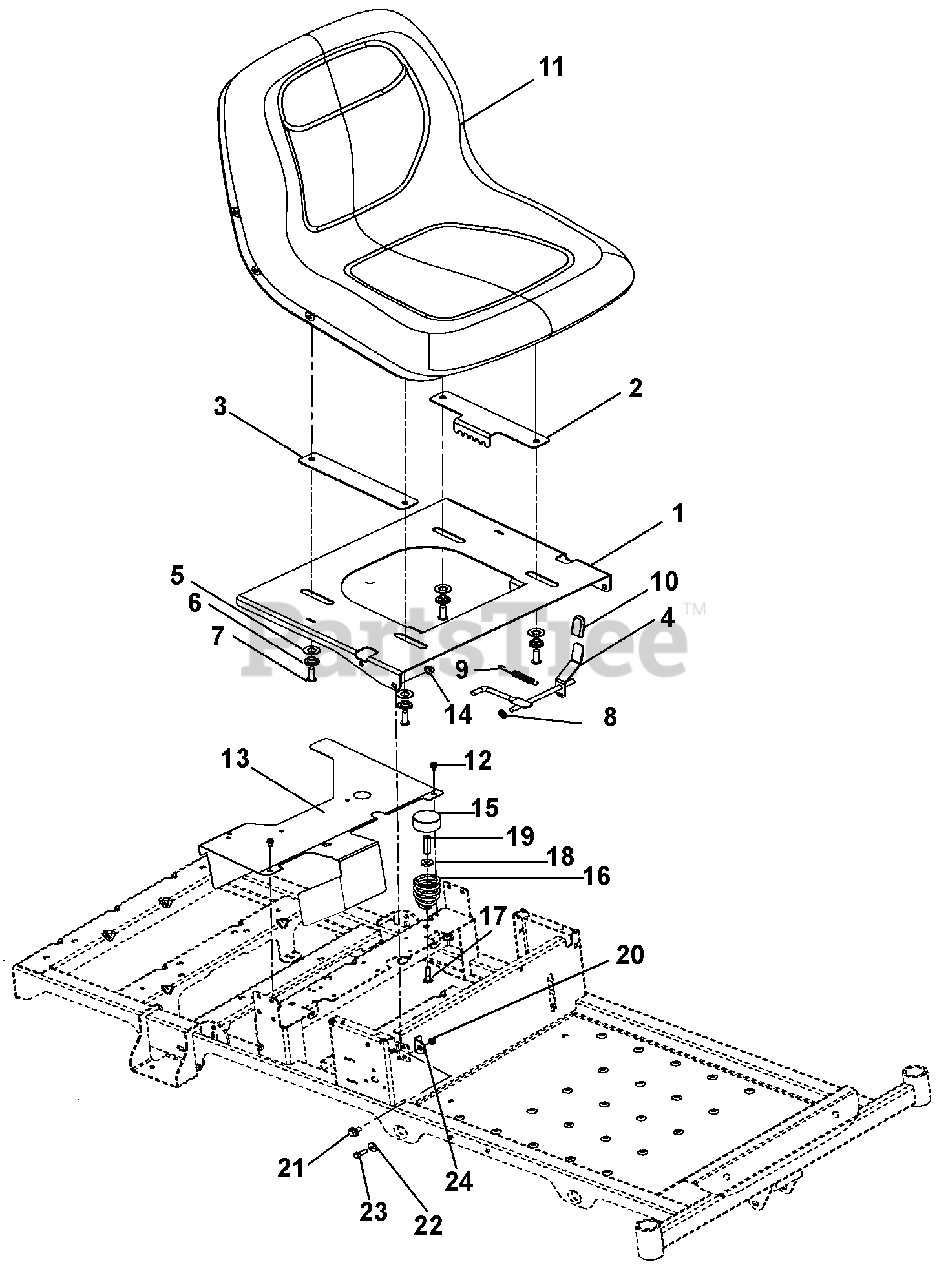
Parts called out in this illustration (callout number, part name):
1	PLATE, SEAT, ADJUSTABLE
2	PLATE, ADJUSTABLE SEAT TRACK
3	PLATE, ADJUSTABLE SEAT SLIDE
4	WLDMT, ADJUSTABLE SEAT LATCH
5	WSHR-FL-STL .505X1.00X.062YWZC
6	BSHG-FLG .32X.500X.344X.880
7	SCR-SKH .31-18X1.0 BTNHD YWZC
8	NUT-PUSH .312
9	SG-TENS .043X.44X3.31 WLD 5.8
10	GRIP, SEAT LEVER, GREY
11	SEAT, MILSCO XB180 GRAY
12	@SCR-TAP .25-20X.50 HWH TR YWZ
13	GUARD, FAN
14	@NUT-LK-TOP-FLG .38-16 YWZC
15	HUB CAP
16	SPRING, SEAT
17	@BLT-RDHDSQNK .31-18X1.50 G5YZ
18	WSHR-FL-STL .328X.87X.179 YWZC
19	NUT, COUPLING 5/16-18 X 1 3/4
20	@NUT-LK-NYL-FLG .31-18 YWZC
21	BOLT-SHLDR .375-16X.150
22	BSHG, FLG .325X.499X.26X.88
23	@BLT-HEX .31-18X1.00 GR5 YWZC
24	BRKT, SEAT STOP
